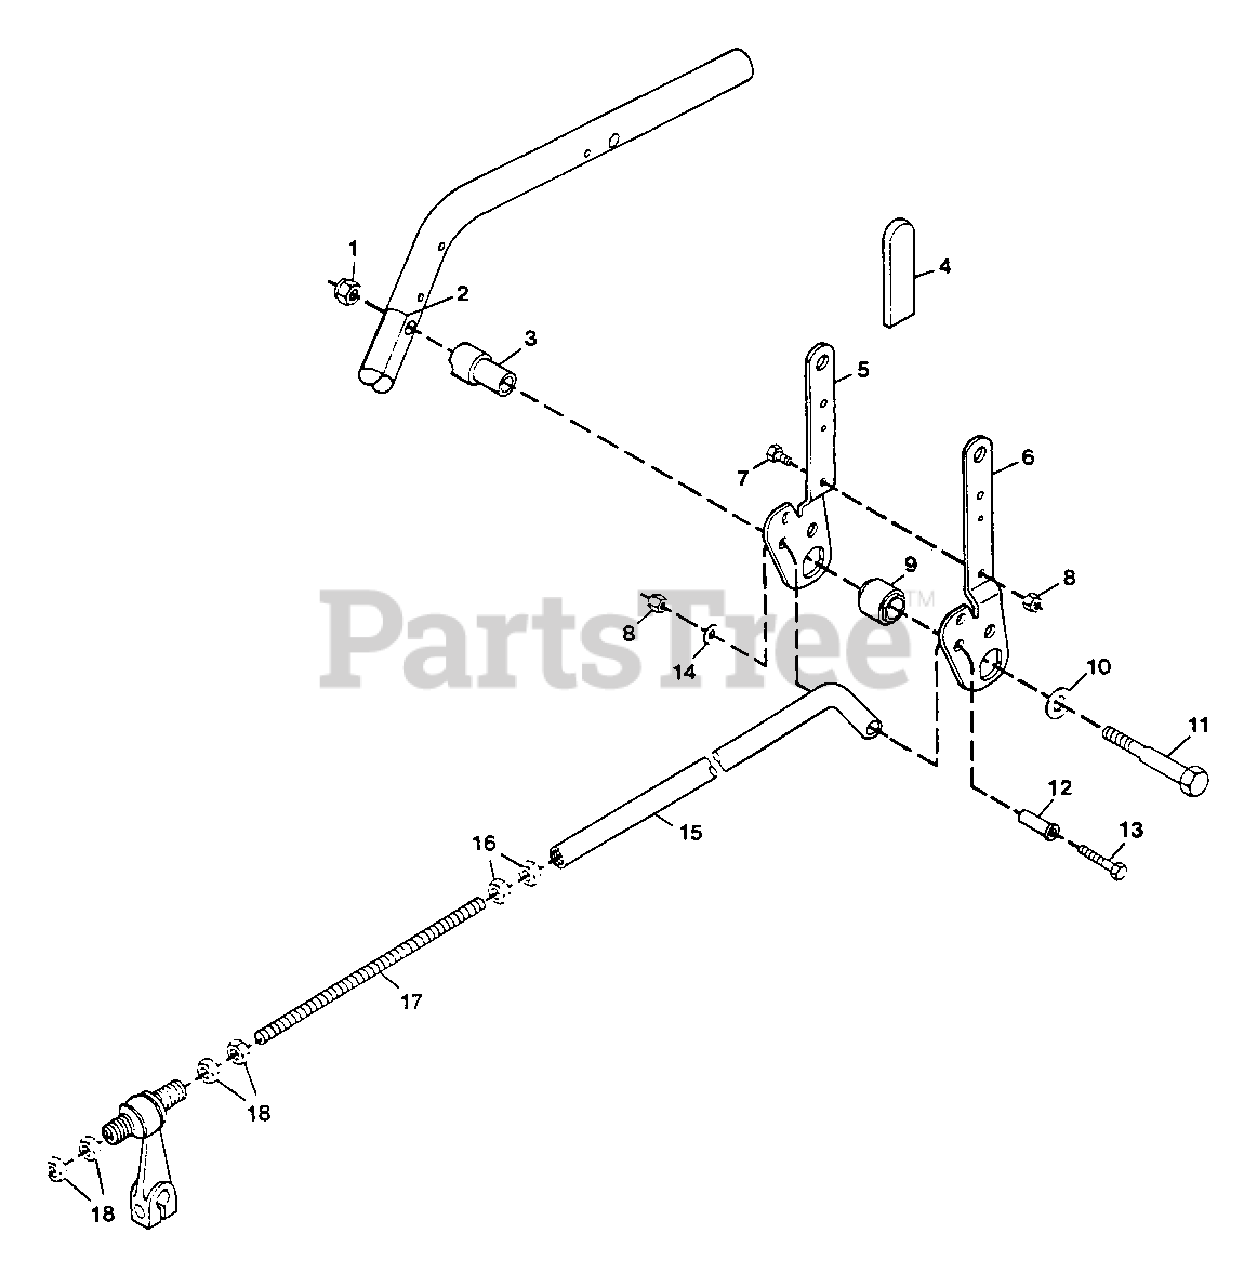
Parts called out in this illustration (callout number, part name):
1	Nut, Lock 3/8-16
2	Decal, Gear Shift
3	Pivot, Hand Lever L.H.
4	Grip, Handle
5	Handle, Control R.H.
6	Handle, Control L.H.
7	Bolt, Hex 1/4-20x.625
8	Nut, Lock 1/4-20
9	Bushing, Handle
10	Washer, Flat .531x1.062x.095
11	Bolt, Hex Step
12	Bushing, Oper. Presence Handle
13	Bolt, Hex 1/4-20x1.50
14	Washer, Flat .281x.625x.065
15	Rod, Control Hi-Lo
16	Nut, Hex 3/6-16
17	Rod, Control Extension
18	Nut, Jam 3/8-16 Hex
